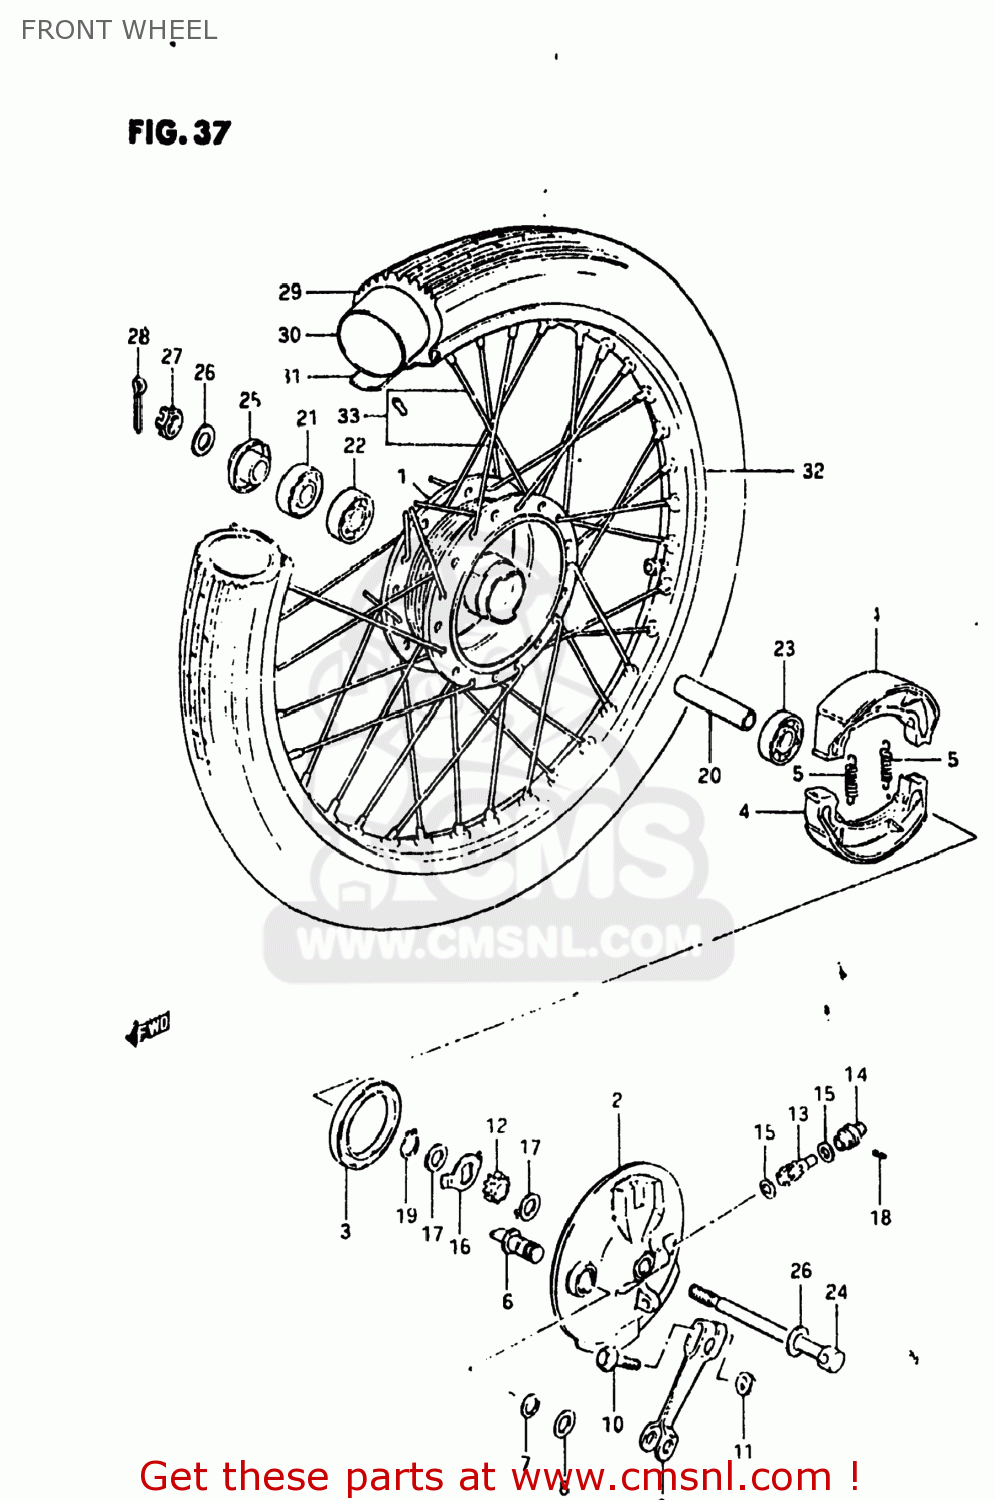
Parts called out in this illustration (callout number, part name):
1	HUB,FRONT
2	PANEL,FRONT BRAKE ANCHOR
3	SEAL,OIL(48X62X7)
4	SHOE,BRAKE
5	SPRING(L:34)
6	CAM,FRONT BRAKE
7	O-RING (D:2.4 ID:13.8)
8	WASHER (14.5X22X1.6)
9	LEVER,FR BRAKE CAM
10	BOLT 6X35
11	NUT
12	GEAR,SPEEDOMETER(NT:24)
13	PINION,SPEEDOMETER
14	BUSH,METER GEAR OUTER
15	WASHER (5.1X9X0.4)
16	DRIVER,SPEEDOMETER GEAR
17	WASHER(18.5X24X1)
18	SCREW
19	CIRCLIP
20	SPACER(12.6X19X47)
21	OIL SEAL(17X38X5)
22	BEARING
23	BEARING
24	AXLE,FRONT
25	SPACER,FR AXLE,R
26	WASHER
27	NUT 12MM
28	COTTER PIN
29	TIRE,FRONT
30	TUBE,INNER
31	PROTECTOR,INNER TUBE
32	RIM,FR WHEEL 1.60X18
33	SPOKE SET,FRONT
